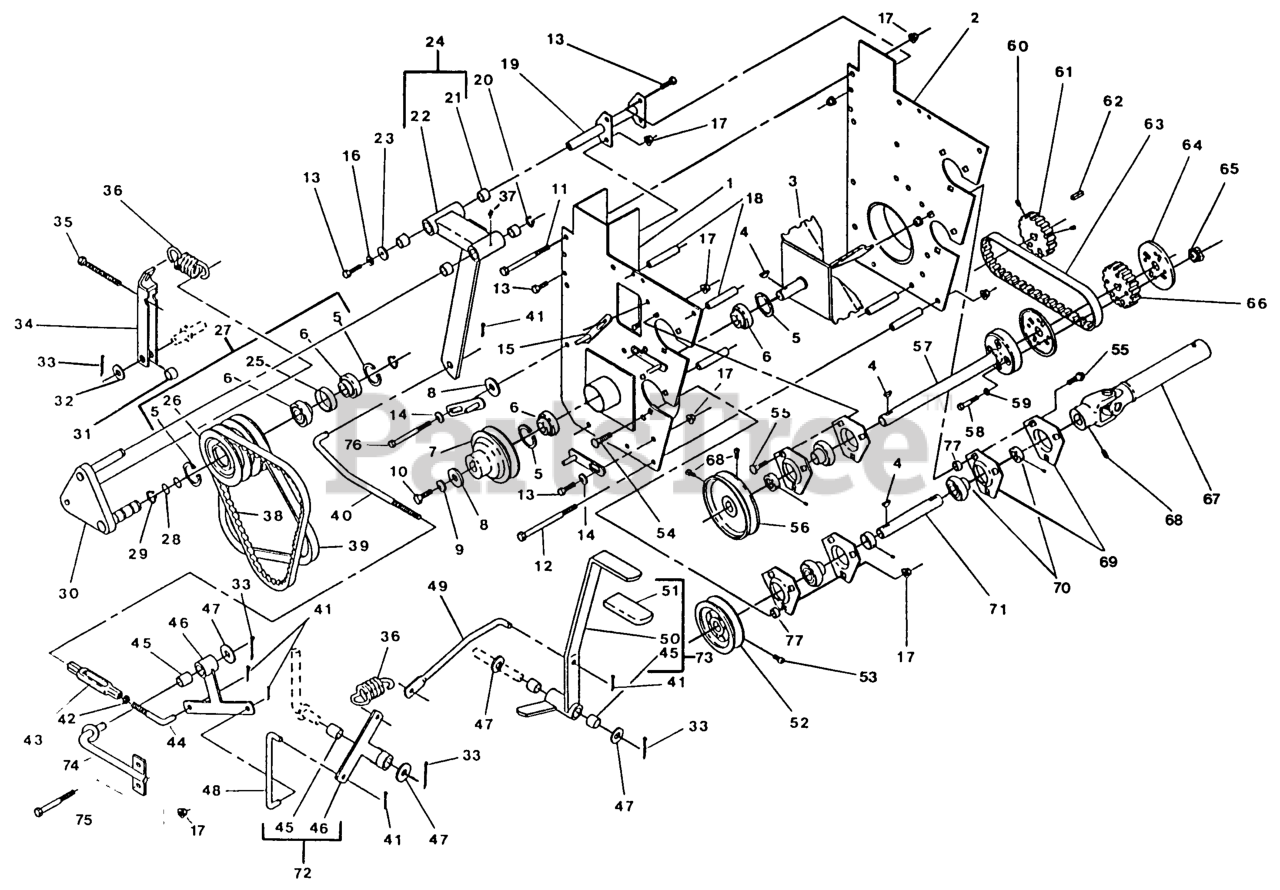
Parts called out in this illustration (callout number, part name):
4	KEY-WOODRUFF
6	BEARING
12	SCREW-HH
14	WASHER-SPRING
15	GUIDE-BELT
16	WASHER-LOCK
22	Control Wldm't - Tmfr. Sheave
24	CNTRL ASSY,TRANS SHV
25	SPACER,TRANSFER BEARING
28	O-RING,
36	SPRING,BELT TENSION
38	BELT,PRIMARY DRIVE
39	BELT,SECONDARY DRIVE
40	ROD,PTO LOW RH THD
44	ROD,PTO RH LOW LH THD
45	SLEEVE-BEARING
49	ROD,PTO UPPER
51	GRIP-LEVER
52	SHEAVE,5.5 B
53	SCREW-SET
59	WASHER-LOCK
63	BELT,DRIVE POSITIVE
69	HOUSING-FLANGE
70	BEARING,W/COLLAR
74	WLD,BELLCRANK SUPPORT
